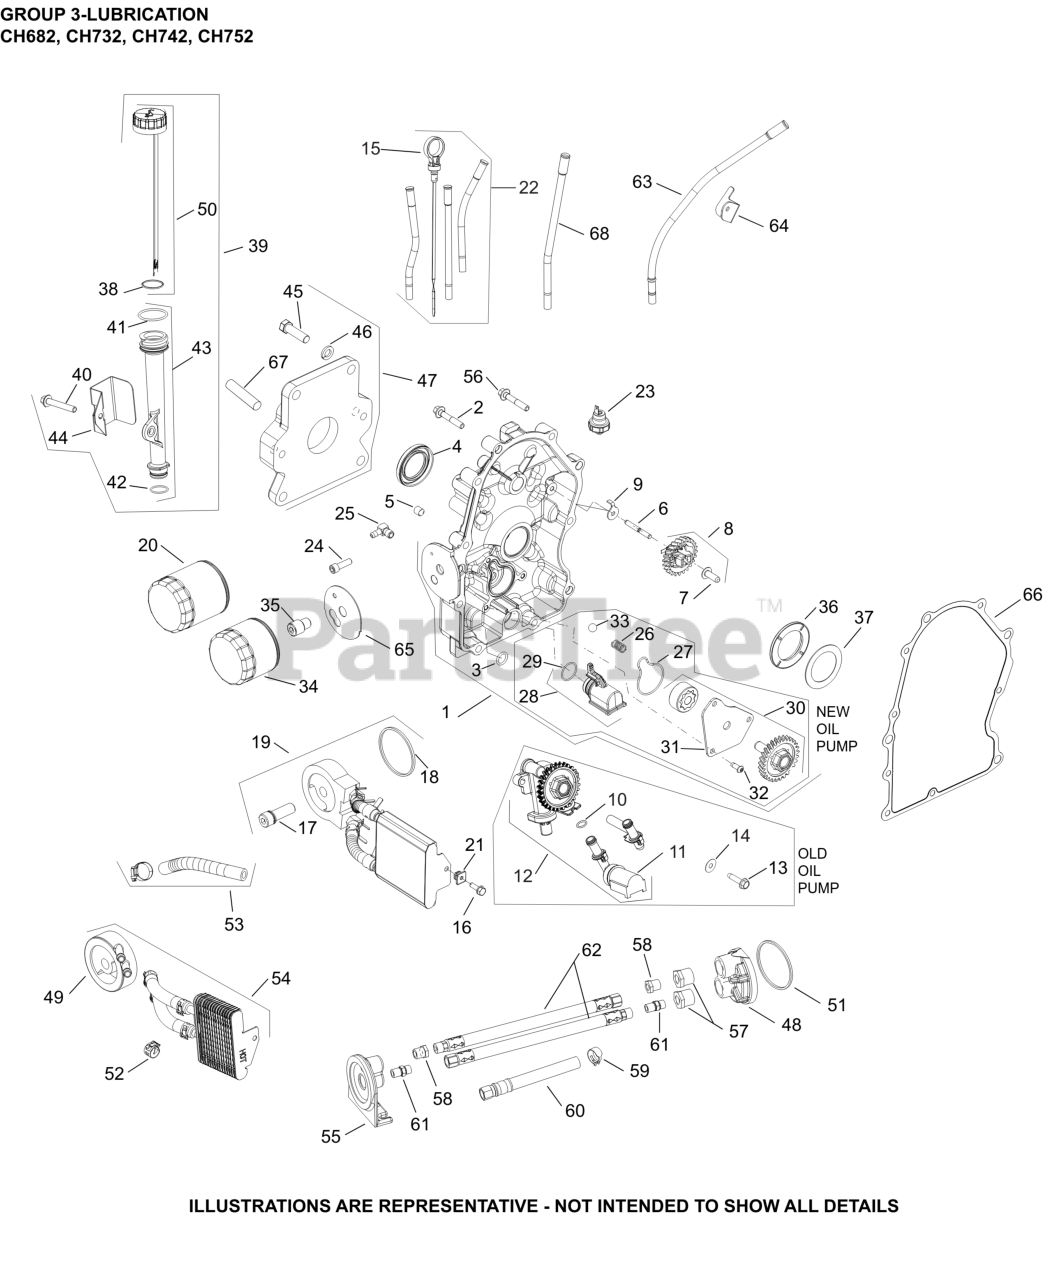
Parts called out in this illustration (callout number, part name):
1	KIT, CLOSURE PLATE ASSY
2	SCREW, FLG M8X1.25X45
5	PLUG, CTSK PIPE 1/8"
6	SHAFT, GOVERNOR GEAR
7	PIN, GOVERNOR REGULATING
8	KIT, GOVERNOR GEAR W/PIN
9	TAB, LOCKING
16	SCREW, TAP M6X1.7X18
17	NIPPLE, OIL FILTER - (#2413608S)
18	O-RING, OIL COOLER
20	OIL FILTER
21	NUT, PLASTIC - BLACK
22	KIT, DIPSTICK/DIPSTICK TUBES
23	SENSOR, OIL PSI
26	SPRING, COMPRESSION
27	SEAL, OIL PUMP COVER
28	PICK-UP ASSEMBLY, OIL
29	O-RING, OIL PICK-UP
30	PUMP ASSEMBLY, OIL
31	COVER, OIL PUMP
32	SCREW, BUTTON HEAD
33	PRESSURE RELIEF BALL
49	ADAPTER, OIL FILTER (CV EFI)
52	CLAMP, HOSE LOW PROFILE
53	KIT, HOSE 140MM
54	COOLER, OIL & DIVERTER ASSEMBLY
56	SCREW, HEX FLANGE
